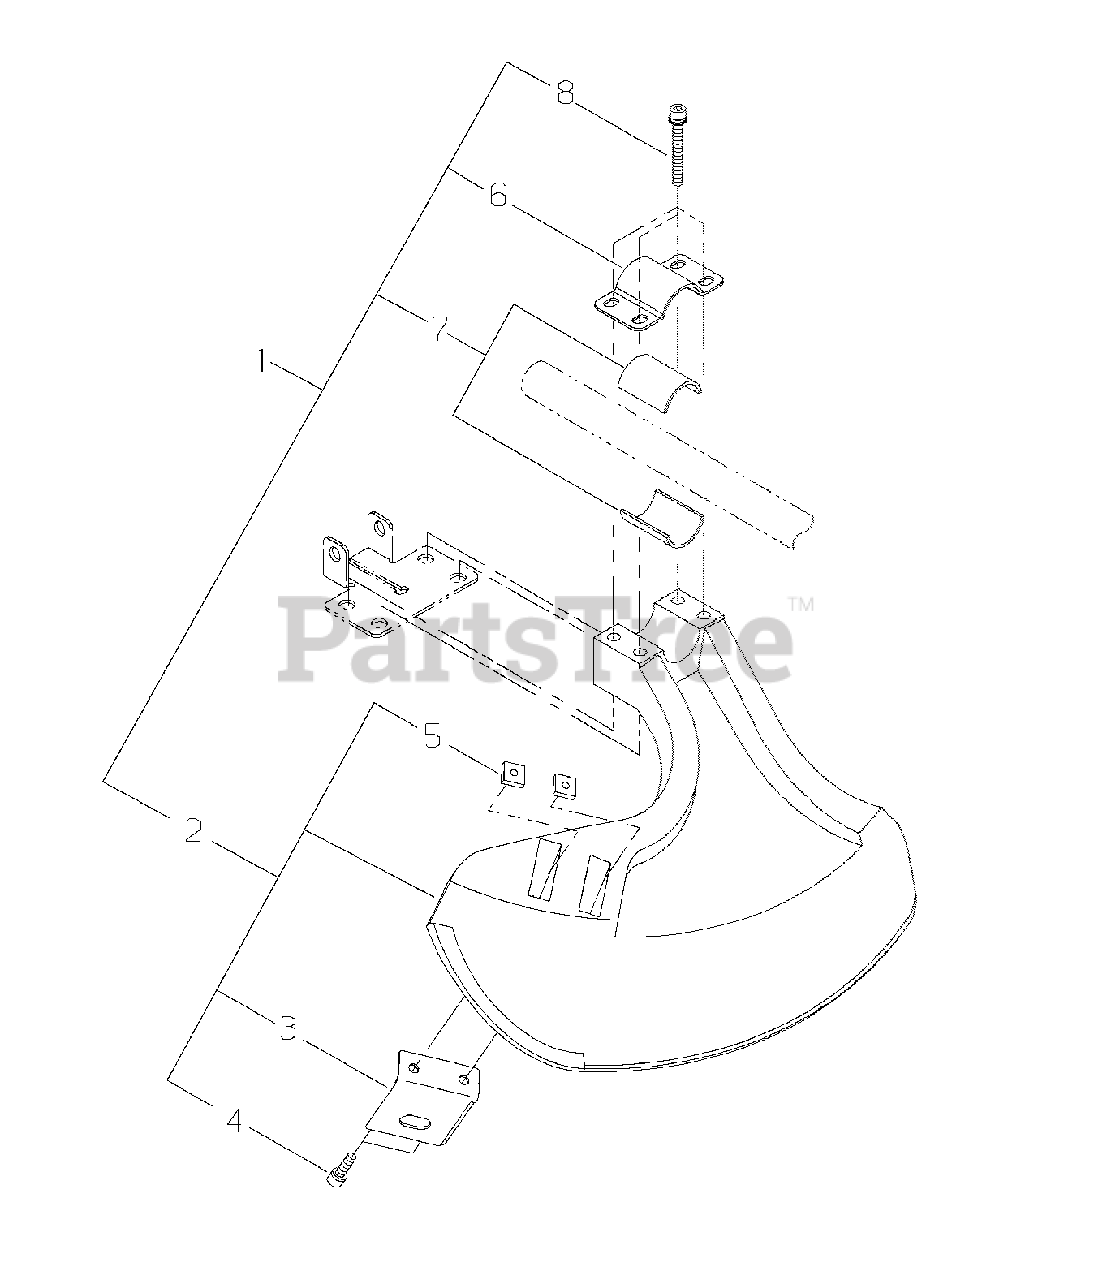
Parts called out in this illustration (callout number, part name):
1	DEBRIS SHIELD KIT
2	DEBRIS SHIELD ASSY
3	KNIFE, TRIMMER LINE
4	SCREW - 5X16
5	NUT - 5
6	CLAMP - UPPER
7	SPACER
8	SCREW - 5X45
